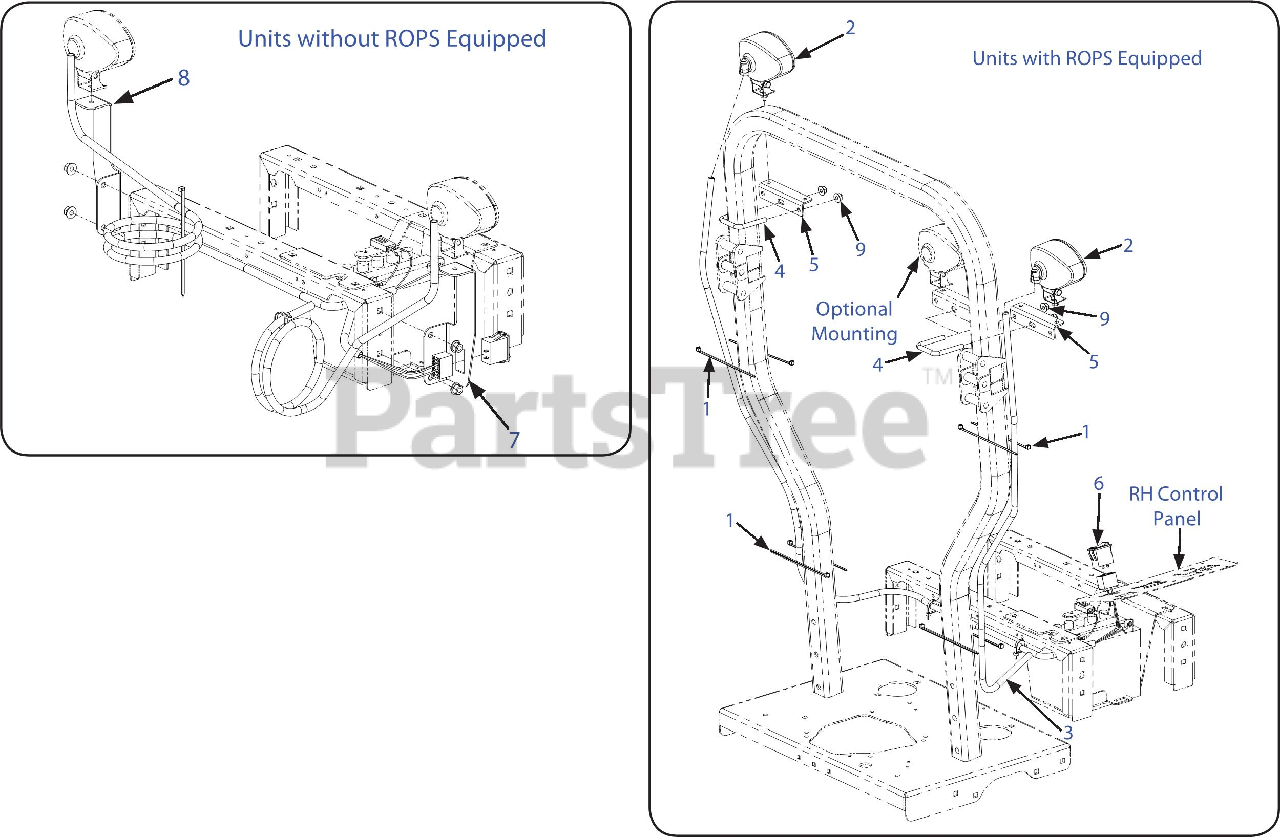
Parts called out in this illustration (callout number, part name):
1	Cable Tie, 3?16 x .05 x 7.4
2	Oval Work Lamp
3	Wire Harness Assembly
4	U-Bolt, 3?8-16 x 2.125
5	Head Lamp Mount
6	Work Light Kit Switch
7	RH Work Lamp Bracket
8	LH Work Lamp Bracket
9	Flange Lock Nut, 3?8-16
